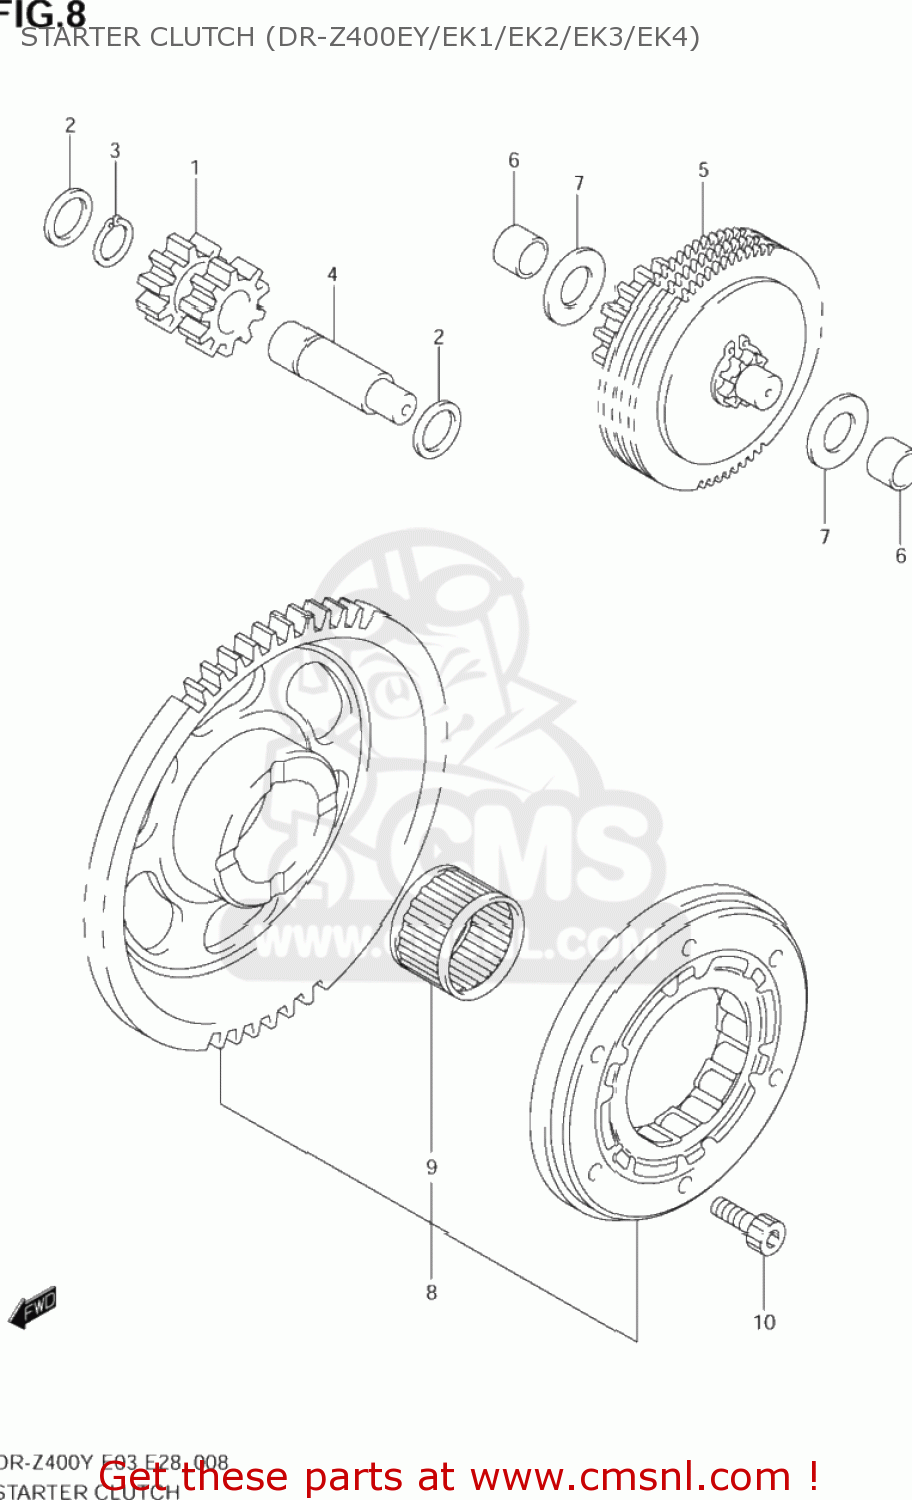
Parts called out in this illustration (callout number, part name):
1	GEAR,STARTER IDLE NO.1
2	SHIM(12X18X0.5)
3	CIRCLIP,12 MM
4	PIN,STARTER IDLE GEAR NO.1
5	LIMITER ASSY,STARTER IDLE GEAR
6	BUSH,LIMITER GEAR SHAFT
7	WASHER
8	CLUTCH SET,STARTER
9	BEARING(25X31X19)
10	BOLT,OIL FILLE
